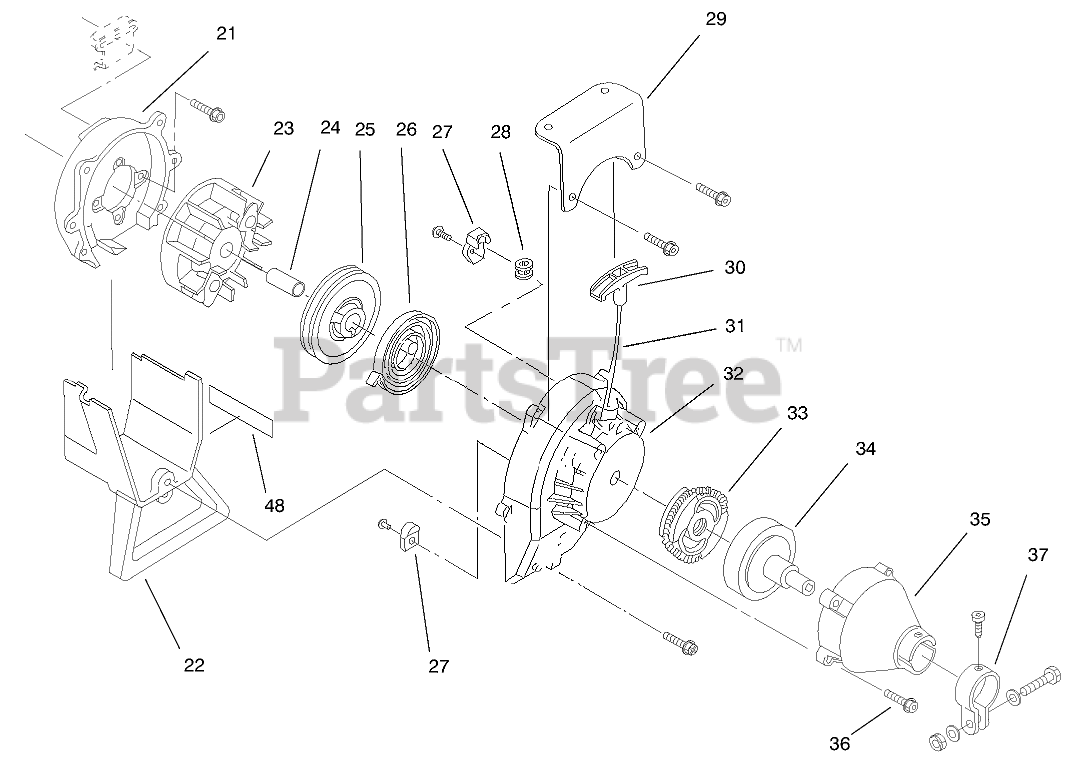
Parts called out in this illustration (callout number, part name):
21	SHROUD ASM
22	Shroud Extension & Stand
23	FLYWHEEL
24	SPACER
25	RECOIL PULLEY ASM
26	RECOIL SPRING
27	PULLEY RETAINER ASM
28	ROPE GUIDE
29	ASM - FUEL TANK GUARD
30	Handle-Pull
32	ASSEMBLY - STARTER HSG
33	Clutch Rotor Asm.
34	CLUTCH DRUM ASM
35	Clutch Cover Asm.
36	CLUTCH COVER SCREW ASM
37	CLAMP ASM - UPPER
48	Decal-Warning
